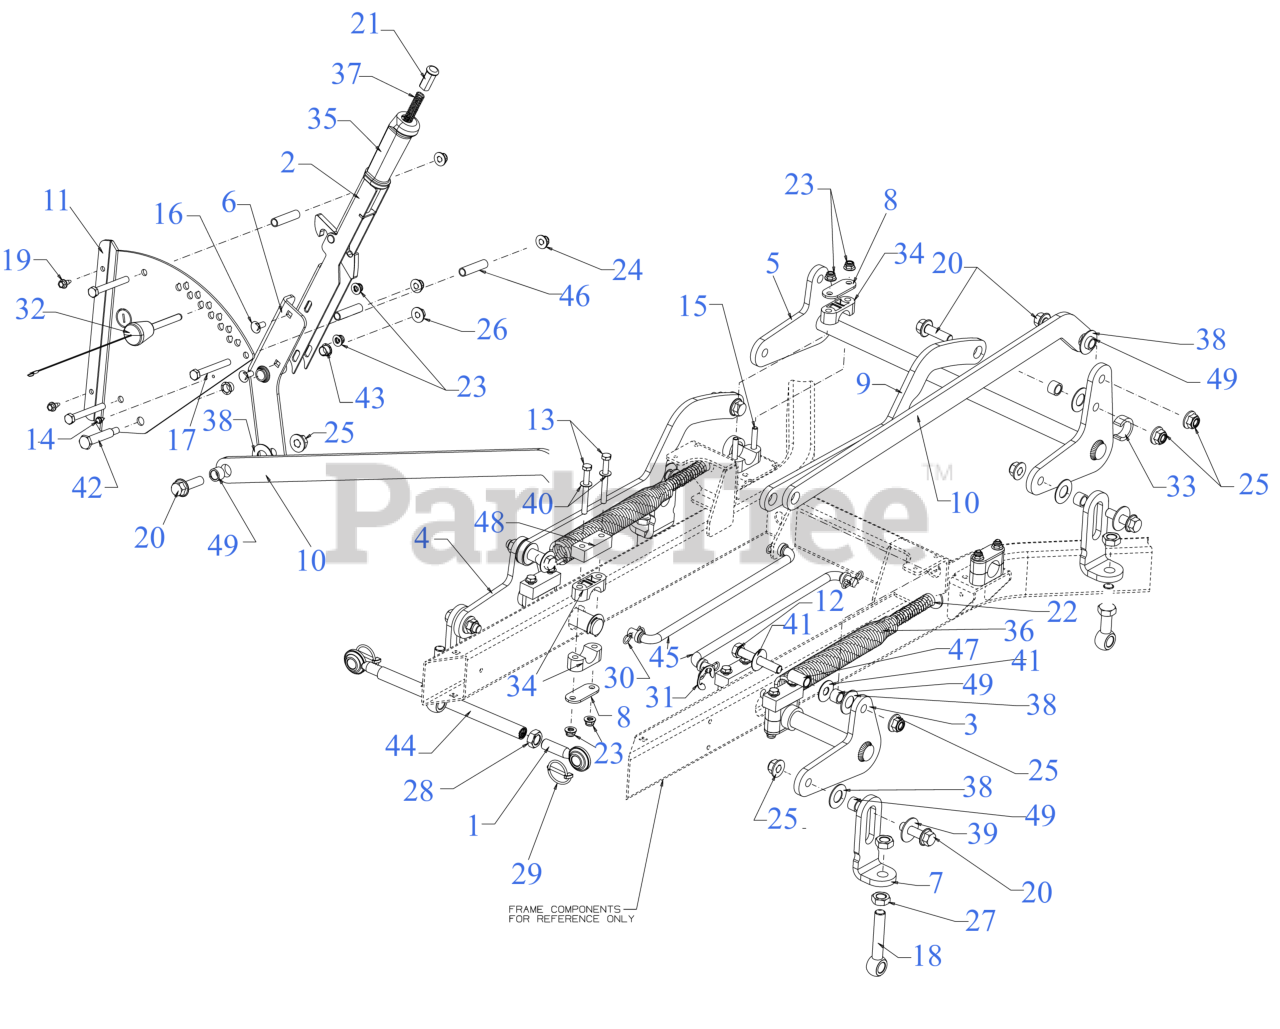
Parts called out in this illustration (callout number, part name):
1	MALE ROD END
2	LATCH HANDLE ASSEMBLY
3	DECK LIFT (RH)
4	DECK LIFT (LH)
5	LIFT ARM SHAFT
6	DECK LIFT HANDLE
7	ADJUSTMENT ARM
8	DECK LIFT REINFORCE PLATE
9	DECK LIFT LINK
10	DECK LIFT LINK
11	DECK LIFT INDEX PLATE
12	SCREW-HEX 1/2-13 x 3.00
13	HEX SCREW 5/16-18 x 3.00
14	HEX SCREW AB-TAP #10 x .50
15	BOLT 5/16-18 x 2.50 GR1
16	CARRIAGE BOLT 5/16-18 x .75
17	SCREW 3/8-16 x 3 GR8
18	EYE BOLT 5/8-11 x 3.63
19	SCREW 1/4-20X.625
20	FLANGE BOLT 1/2-13:1.75:GR5
21	LIFT HANDLE BUTTON
22	SPRING INSERT SCREW
23	FLANGE LOCK NUT 5/16-18
26	FLANGE LOCK NUT
28	HEX JAM NUT 5/8-18
29	LYNCH PIN .1875
30	BOW TIE COTTER PIN
31	E-RING 1.50 OD
32	MAGNETIC DECK LOCK KNOB
33	SNAP SPACER
34	DECK LIFT SHAFT BUSHING
35	LIFT HANDLE GRIP
36	EXTENSION SPRING 1.44 OD x 11.36
37	COMPRESSION SPRING
38	FLAT WASHER .760ID X1.49OD x .06
39	WASHER .51 x 1.5 x .07
40	FLAT WASHER
41	FLAT WASHER
42	SHOULDER SCREW .50 x 2.23 3/8-16
43	NYLINER BEARING
44	TUBE .565x.75x10.375"
45	DECK CONTROL ROD
46	SPACER .38 ID x .50 OD x 2.06 LG
48	RECTANGLE SPACER
